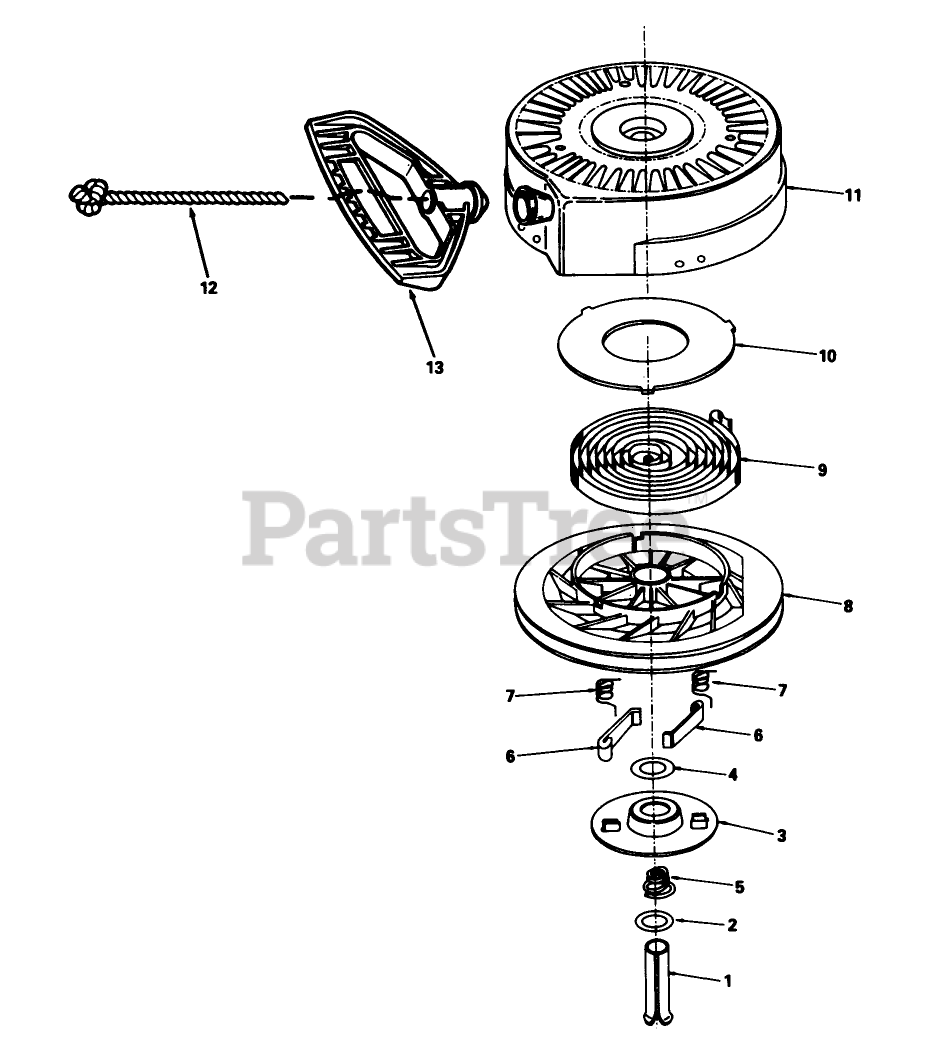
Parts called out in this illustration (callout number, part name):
1	Pin, Spring (Incl. Ref. #7)
2	Washer
3	Retainer
4	Washer
5	Brake Spring
6	Dog-Starter
7	Spring-Dog
8	Pulley
9	Rewind Spring
10	Cover-Spring
11	Housing Assembly
12	Rope-Starter
13	Handle-Starter, Mitten Grip
